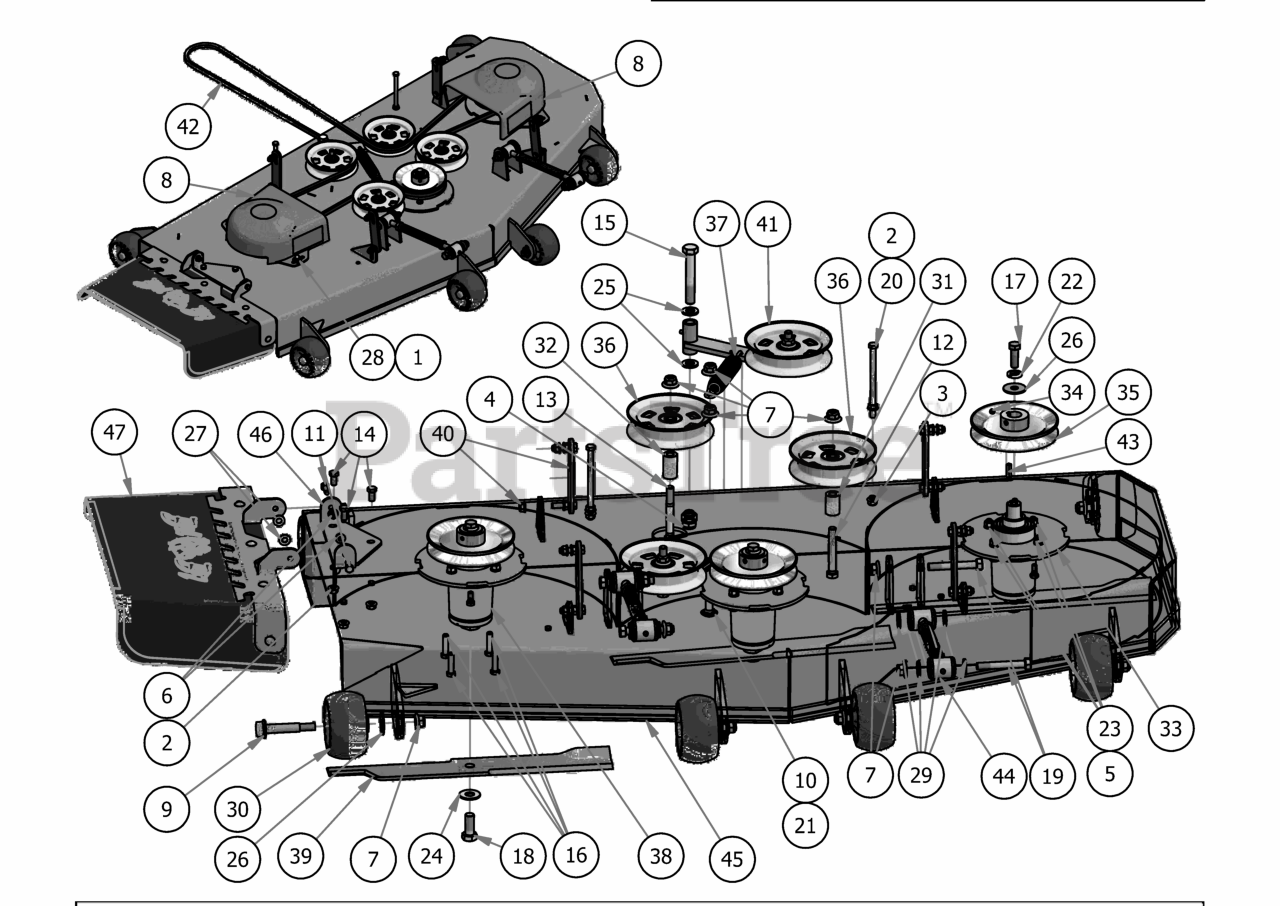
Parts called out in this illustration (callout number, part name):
1	Acorn nut-pulley Cover
2	3/8" Flange Nut
3	3/8" Nylock Flange Nut
4	5/8-11 Nylon Insert Jam Half Nut
5	3/8" Hex Nut
6	5/16" Nylon Flange Nut
7	1/2-13 Nylon Flange Nut
8	Pulley Cover
9	Deck Wheel Bolt
10	1/2 x 2" Carriage Bolt
11	5/16-18 x 1 GR 5 Hex Bolt Zinc
12	1/2 x 3 1/2 Flange Bolt Grade 8
13	1/2" x 4" Bolt (Grade 8)
14	3/8" x 3/4" Hex Bolt
15	5/8" x 4" Hex Bolt
16	3/8 x 1.5" Bolt
17	1/2"-20 x 1 1/2 - Grade 5 Fine Thread Bolt
18	5/8 x 1 1/2 Grade 8 Hex Bolt (Fine)
19	1/2-13 x 3 1/2 GR 5 Hex Bolt
20	3/8-16 x 5 1/2 Hex Bolt
21	.517 Square Hole Round Washer
22	1/2" Lock Washer Zinc
23	3/8" Lock Washer
24	5/8'' Flat Washer
25	.630 ID Plastic Washer
26	1/2" Belleville Washer
27	.360 ID Plastic Washer
28	.360 ID Plastic Washer-Black
29	.505 Nylon Spacer
30	Deck Wheel
31	.502 ID X .750 OD X 1.500 Long Spacer
32	1 3/4" Pulley Spacer
33	Deck Spindle Support Plate
34	5/16 Set Screw
35	6 1/4" Drive Pulley
36	5-3/4 Idler Pulley
37	Deck Idler Spring
38	Spindle Assembly
39	60 Inch Fusion Blade
40	Deck Hanger Assembly
41	2017 MZ/ZT Deck Idler Assembly
43	1/4" x 1" Key
44	2018 Maverick Turnbuckle (Top Link)
45	60 ZT Welded Deck Shell
46	Discharge Chute Hanger (deck mounted)
47	Discharge Chute Assembly
